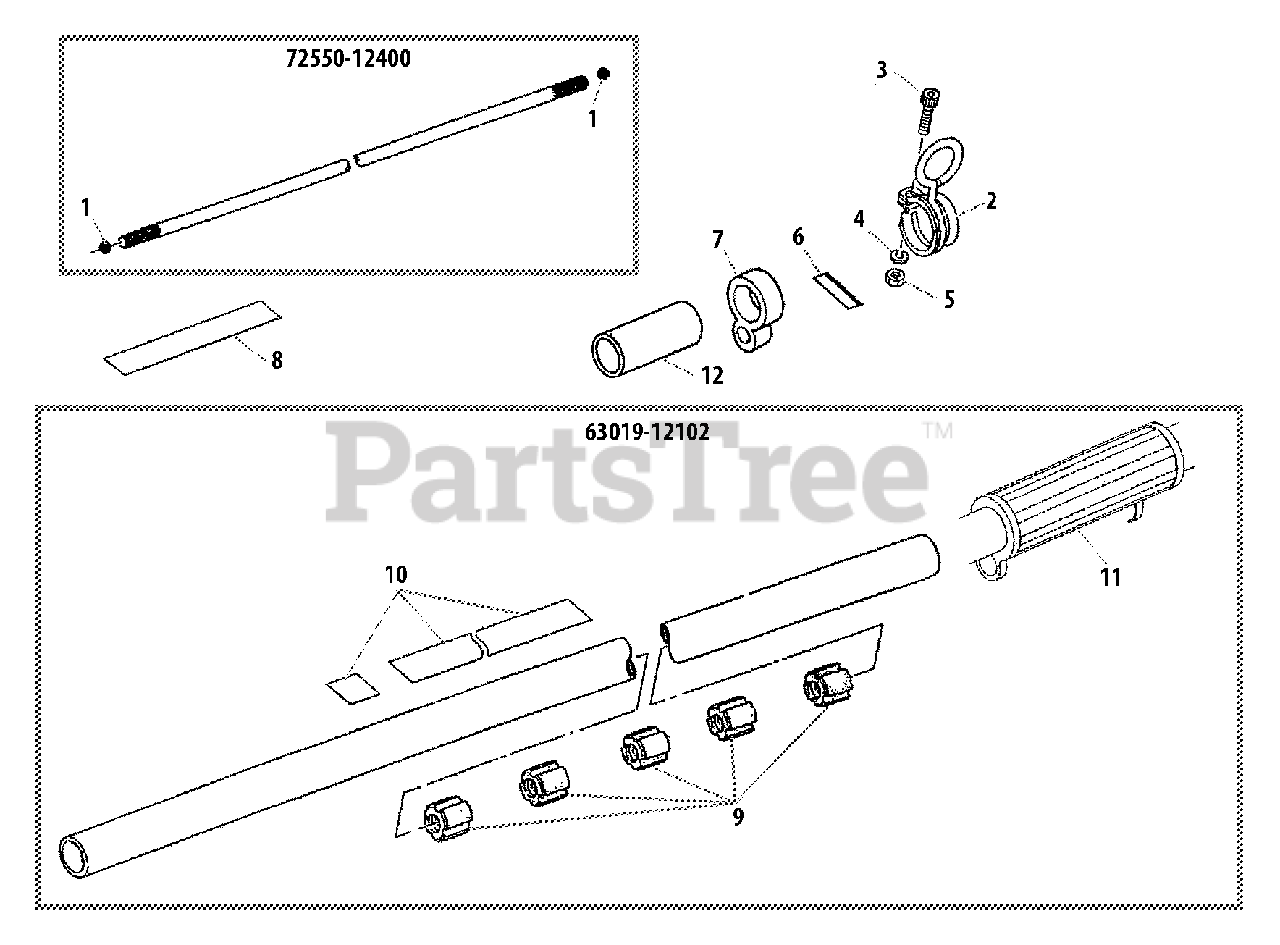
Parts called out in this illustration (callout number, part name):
1	STOPPER
2	HANGER
3	BOLT 5×12
4	LOCKWASHER
5	NUT M5
6	LABEL - ALIGNMENT
7	HOLDER, CABLE
8	LABEL - MODEL
9	BUSHING
10	LABEL
11	GRIP
12	PROTECTOR
63019-12102	MAIN PIPE ASSY
72550-12400	DRIVESHAFT ASSY
